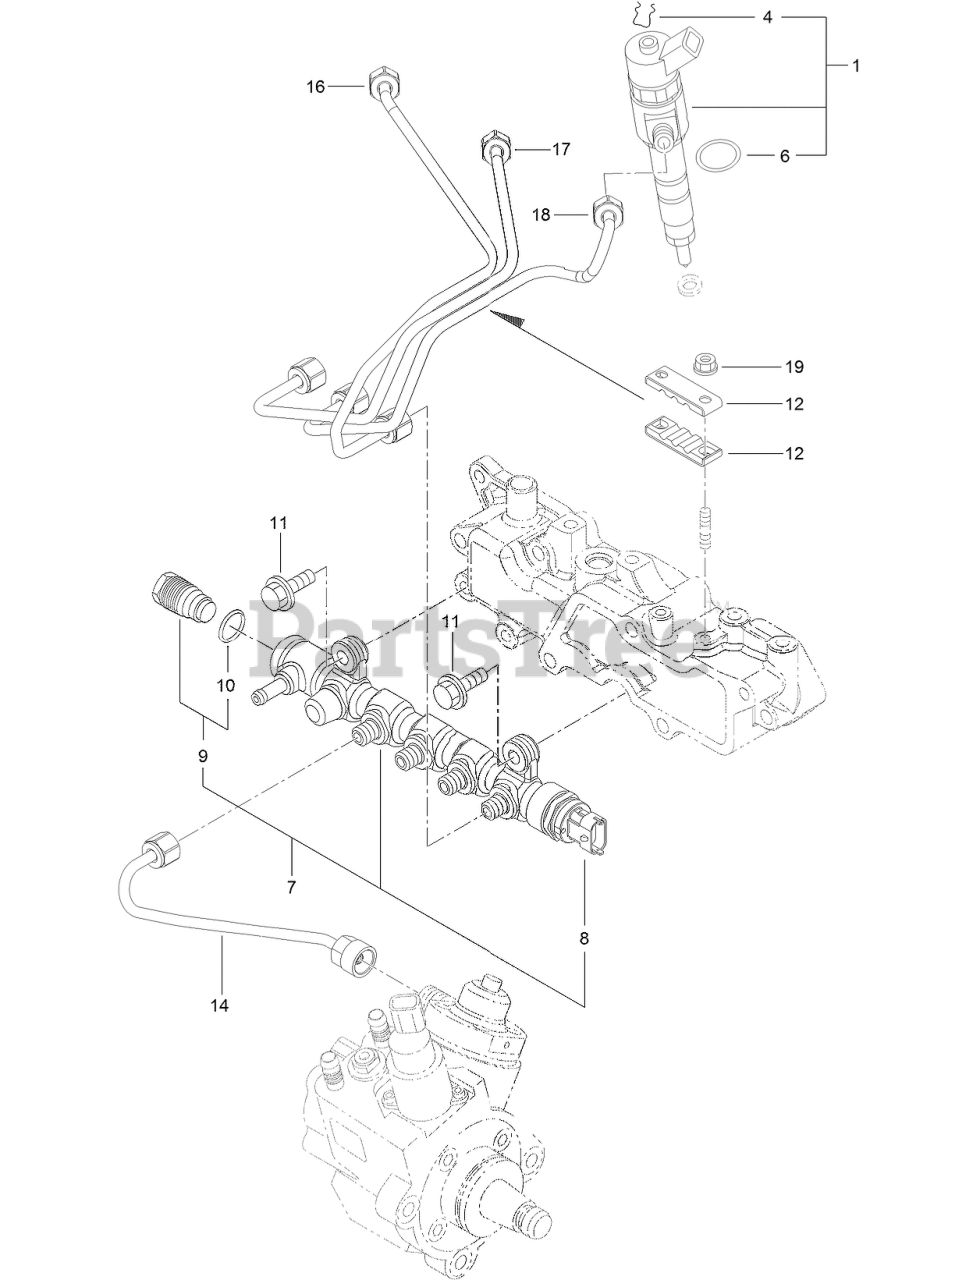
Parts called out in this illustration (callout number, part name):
1	INJECTOR ASM
4	RING-RETAINING
7	RAIL ASM
8	Sensor-Pressure, Rail
9	Valve ASM
12	RETAINER
14	RAIL IN PIPE ASM
16	INJECTION PIPE ASM
17	INJECTION PIPE ASM
18	INJECTION PIPE ASM
